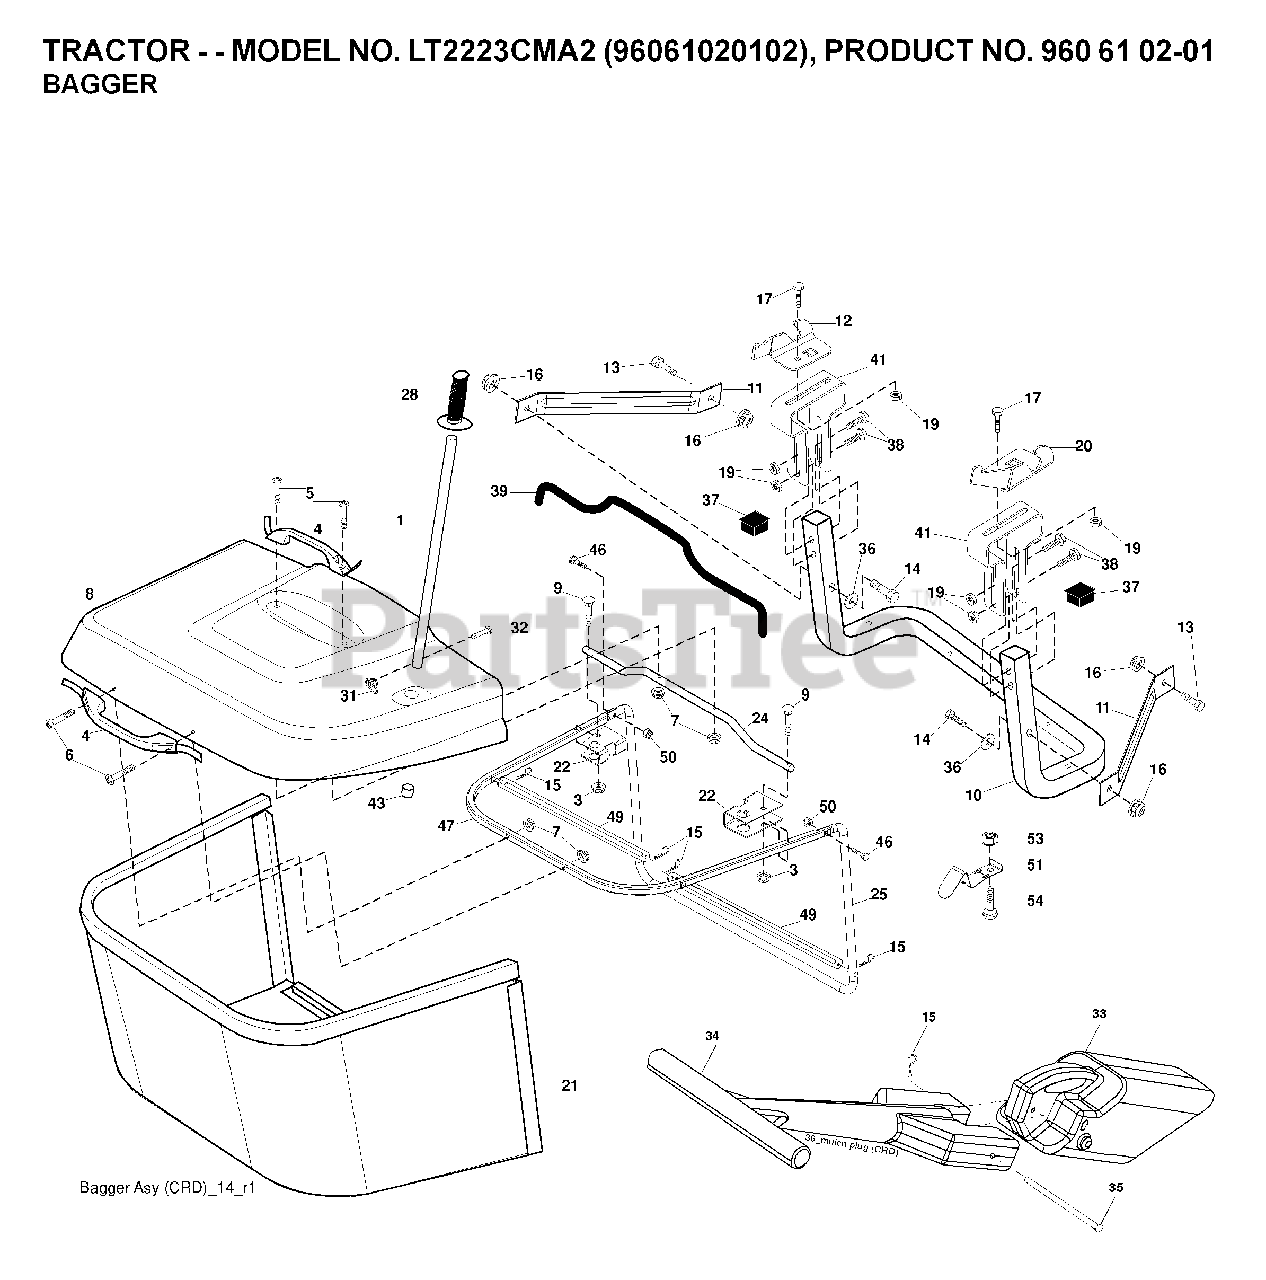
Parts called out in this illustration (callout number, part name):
1	TUBE HANDLE
3	NUT T
5	SCREW.PAN.HEAD
11	BRACKET
14	BOLT-HEX EAK
15	RETAINER-SPRNG RB
16	NUT LOCK FLG 3/8-16 UNC
17	BOLT
19	NUT LOCK HEX FLANGE 5/16-18
20	BRKT.PIVOT.RH.CRD
21	BAGGER.ASM.CRD.2007
22	BRACKET
24	TUBE
28	GRIP.HANDLE.BLACK
31	RETAINER CLIP
32	RIVET,DRILLED
33	MULCH PLUG, CTH150
35	PIN
38	BOLT.5/16-18X2.5
39	SEAL.BAGGER.CRD
41	BRKT, BAGGER
43	PLUG, TUBING END
46	BOLT.CARRIAGE.5/16-18
50	NUT.71038.31-18.HEX.NYLOCK
53	NUT
54	BOLT
